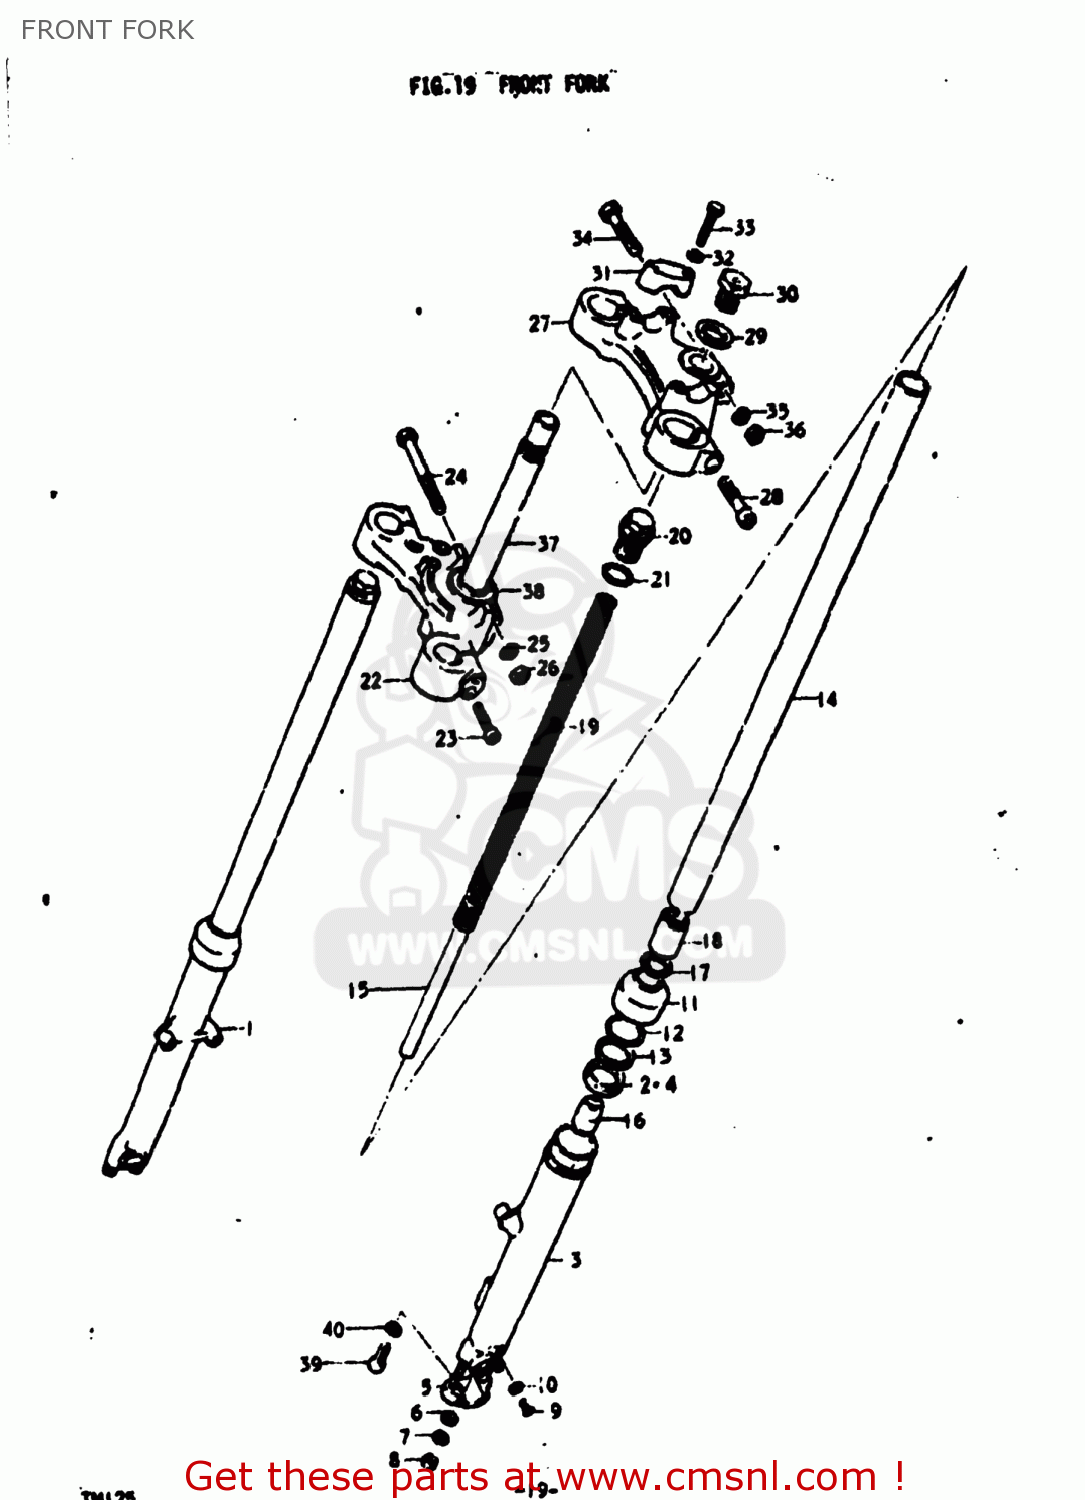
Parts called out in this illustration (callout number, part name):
1	TUBE,OUTER,LEFT
2	SEAL,OIL
3	CYLINDER,FRONT FORK
4	TUBE,FORK,INNER
5	PISTON
6	SNAP RING
7	O-RING,FORK INNER TUBE
8	STEM,STEERING
9	STEM,STEERING
10	RACE,STEERING OUTER LWR
11	SPRING
12	GASKET,DRAIN,PLUG (NAS)
13	GASKET
14	SEAL,DUST
15	HEAD,STEERING STEM
16	HOLDER,HANDLEBAR
17	HOLDER,AXLE
18	BOLT,FR FORK
19	BOLT
20	BOLT 10X50
21	Bolt
22	CAP
23	BOLT
24	BOLT
25	BOLT
26	SCREW
27	NUT
28	NUT (8MM)
29	LOCK WASHER
30	WASHER,STEM HEAD
31	WASHER
32	GUIDE,SPRING
33	PIECE,OIL LOCK
34	RING,SNAP
35	BOLT,STUD
36	RING,SNAP
